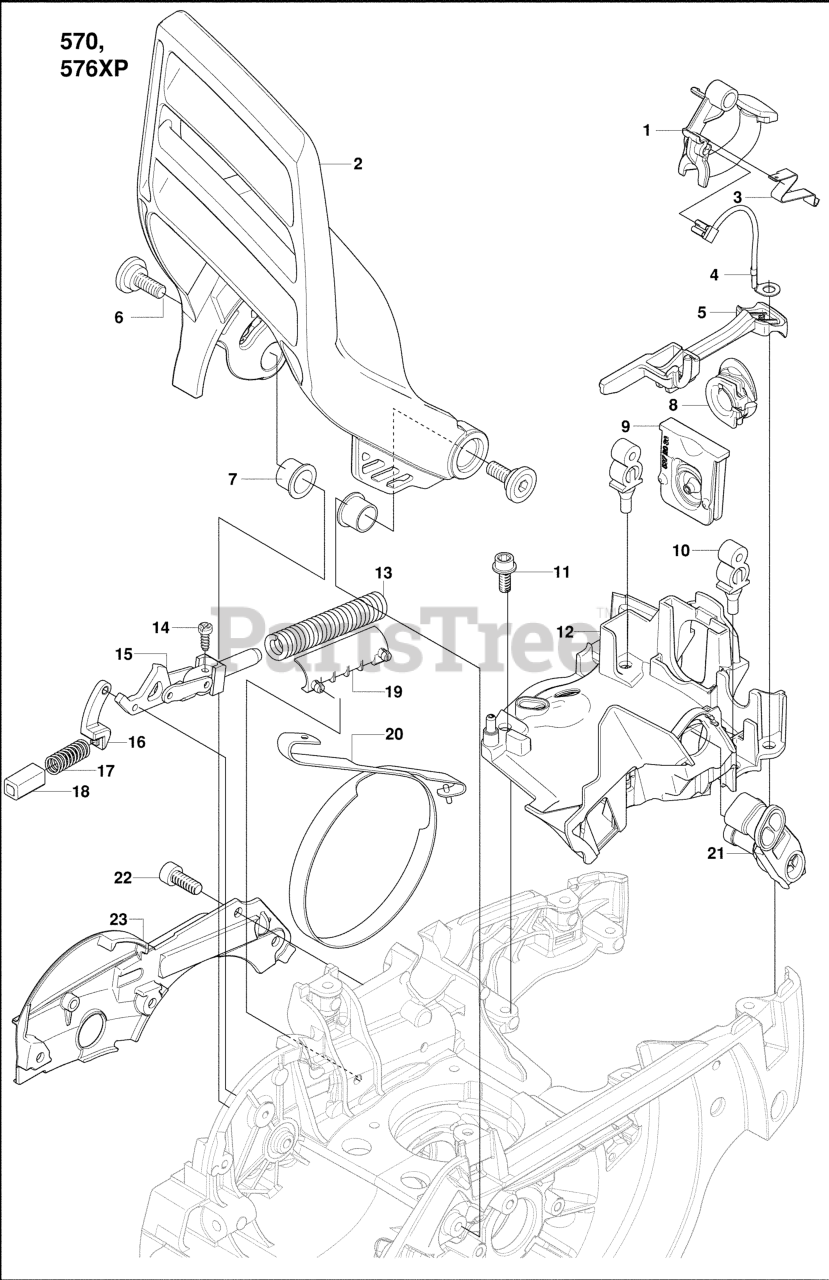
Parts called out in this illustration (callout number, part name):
2	CHAIN BRAKE
5	CHOKE CONTROL
10	SUPPORT
13	BRAKE SPRING
15	KNEE JOINT
17	LOCK SPRING
19	%SUPPORT
20	BRAKE BAND
